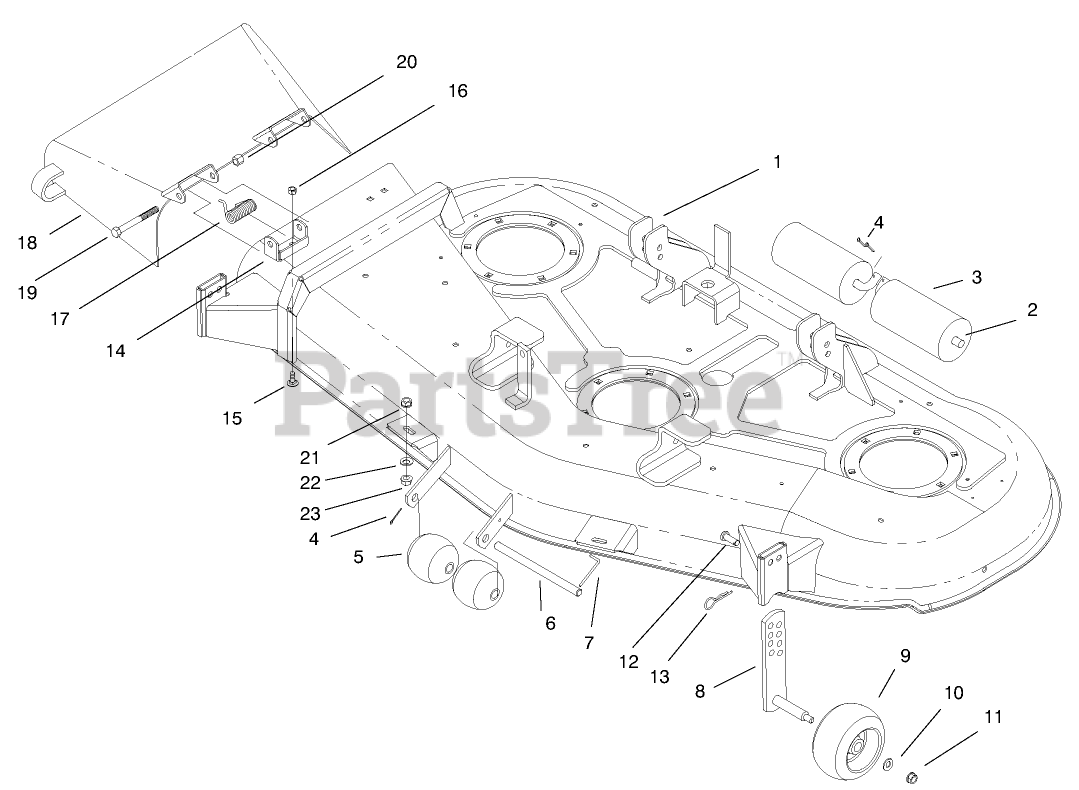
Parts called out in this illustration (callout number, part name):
1	ASM - 52 DECK W/DECALS
2	SHAFT-ROLLER, REAR
3	ROLLER-DECK
4	PIN-COTTER
5	ROLLER
6	SHAFT-ROLLER
7	PIN-SPECIAL
8	GAGE-WHEEL
9	WHEEL-GAGE
10	WASHER-FLAT
11	NUT-LOCK, NI
12	PIN-CLEVIS
13	PIN-HAIR
14	Bracket-Pivot
15	SCREW-CARR
16	NUT-LOCK, CONE
17	SPRING
18	ASM - DEFLECTOR W/DECALS
19	SCREW-HH
20	NUT-HEX
21	NUT-LOCK, NI
22	WASHER-FLAT
23	NUT-FLANGE
